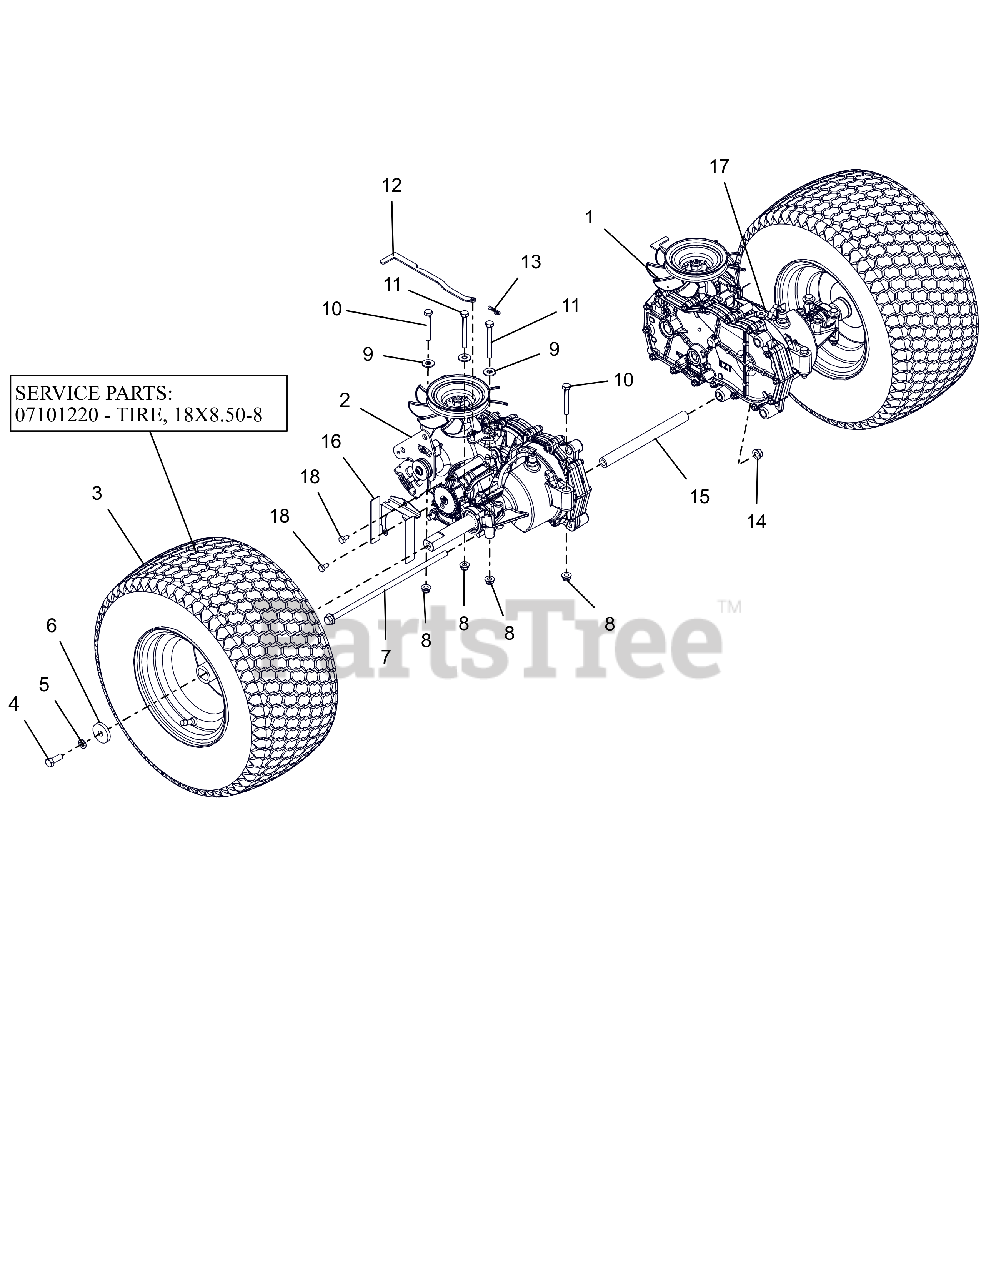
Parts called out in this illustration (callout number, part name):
1	TRANSAXLE EZT D-SHFT SHORT
2	TRANSAXLE EZT D-SHFT SHORT
3	ASM, WHL/TIRE 18X8.50-8 DHUB
3	TIRE, 18X8.50-8
4	BLT, HEX .38-16X1.00 G8ZCCEP30
5	WSHR,LK-REG .375X.094 ZCC
6	WSHR, FLT .406X1.50X.245 ZCC
7	BLT,HEX-FLG .38-16X11.5 G5 ZCC
8	NUT,LK-NYL-FLG .31-18 G5ZC120
9	WSHR,FLT .375X.875X.083 ZCC
10	BLT, HEX .31-18X2.25 G5 ZCC
11	BLT, HEX .31-18X2.75 G5 ZCC
12	BRKT, DUMP VALVE
13	PIN, HAIR #213 .08X1.19 ZCC
14	NUT-LK-CTR-FLG .375-16 GF ZCC
15	TUBE, TRANSAXLE BRACE 8.18LG
16	GUARD, PARKING ,BREAK RH (GREY PEARL)
17	GUARD, PARKING BRAKE LH (GREY PEARL)
18	BLT,HEX .25-20X.50 G5 ZCC
